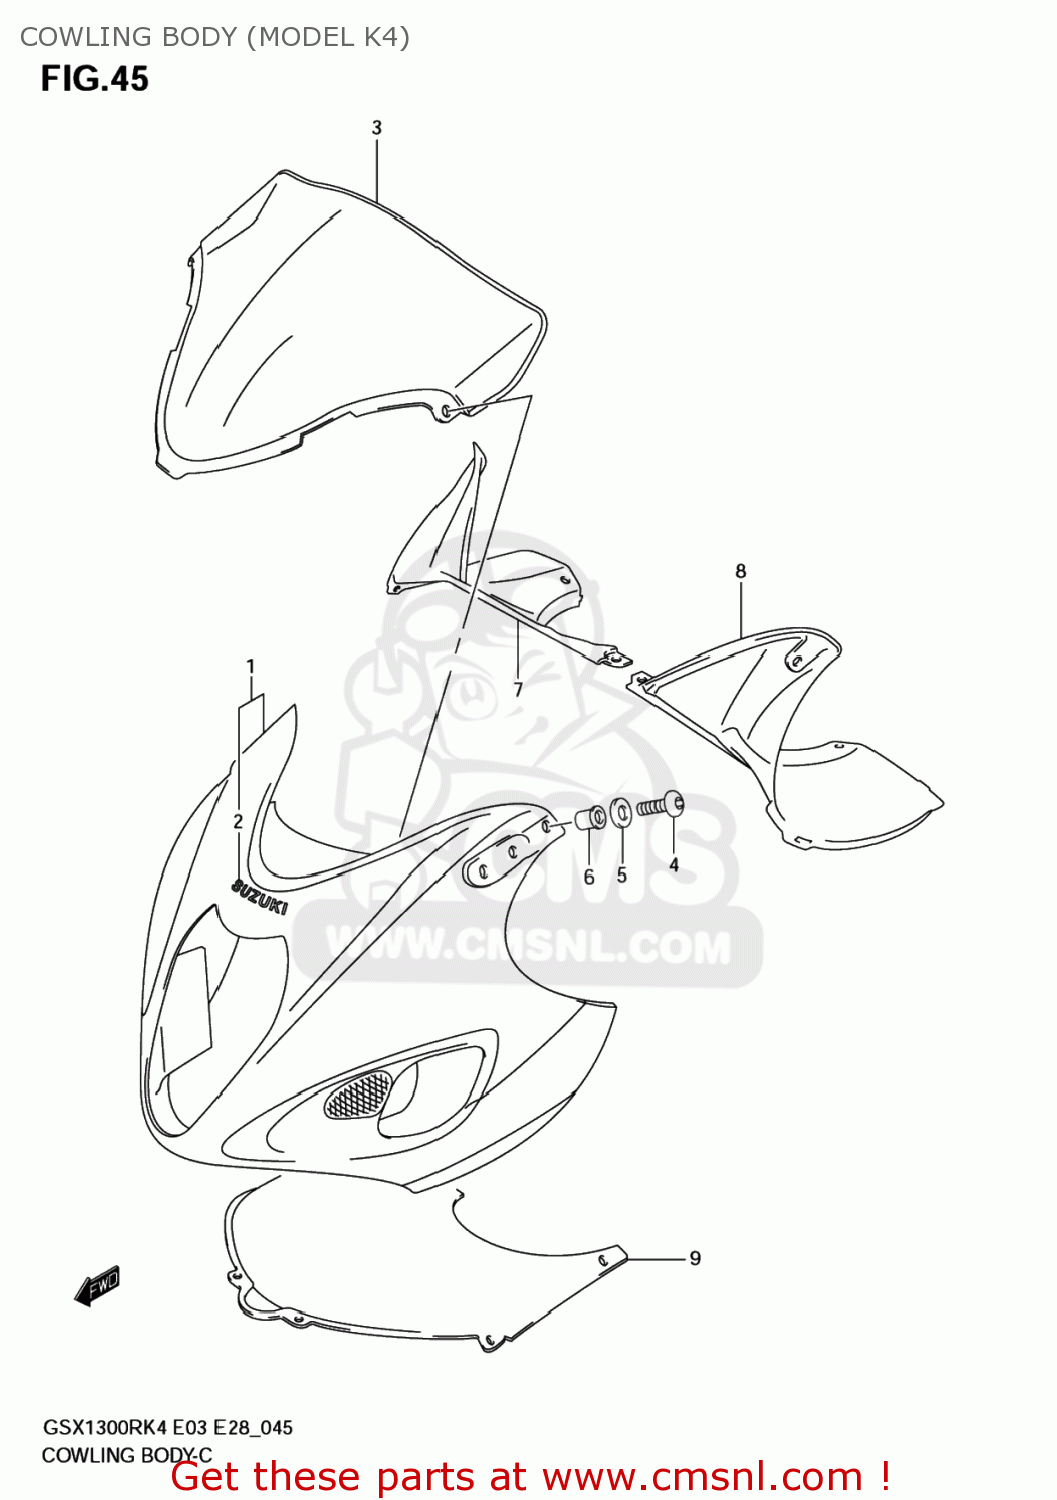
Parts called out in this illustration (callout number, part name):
1	COWLING ASSY,BODY
2	EMBLEM,SUZUKI
3	WINDSCREEN
4	SCREW(5X14)
5	WASHER
6	NUT
7	PANEL,UPR,R
8	PANEL,UPR,L
9	COVER,BODY COWLING
